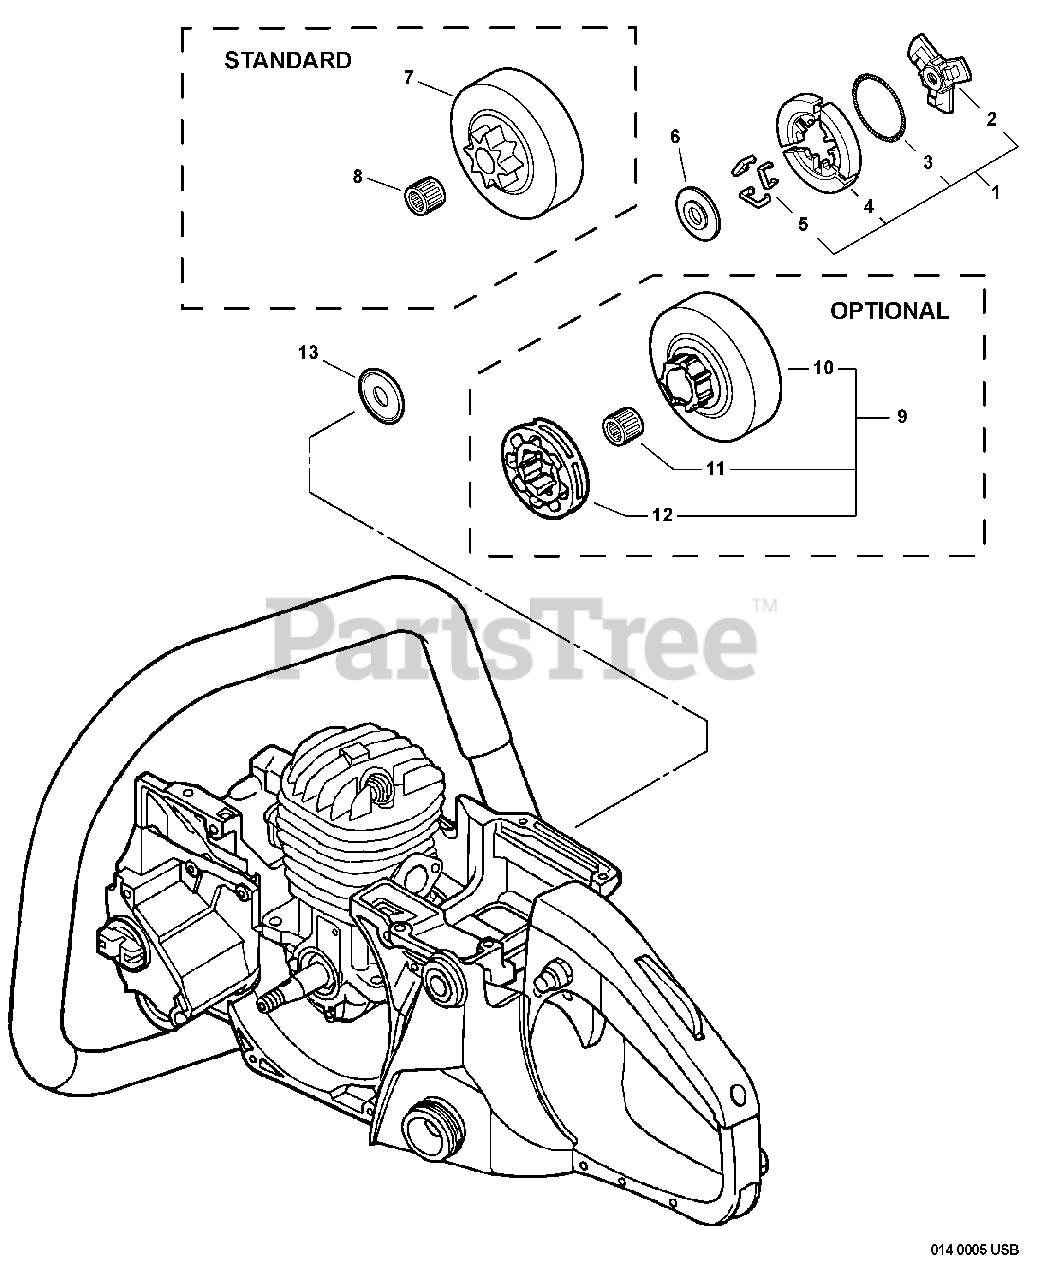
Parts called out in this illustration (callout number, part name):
1	CLUTCH ASSY
2	HUB, CLUTCH
3	SPRING, CLUTCH
4	CLUTCH SHOE SET
5	CLIP, SPRING
6	PLATE, CLUTCH
7	DRUM, CLUTCH
8	BEARING, NEEDLE
9	RIM SPROCKET KIT
10	DRUM, CLUTCH
11	BEARING, NEEDLE
12	SPROCKET, RIM
13	PLATE, CLUTCH
